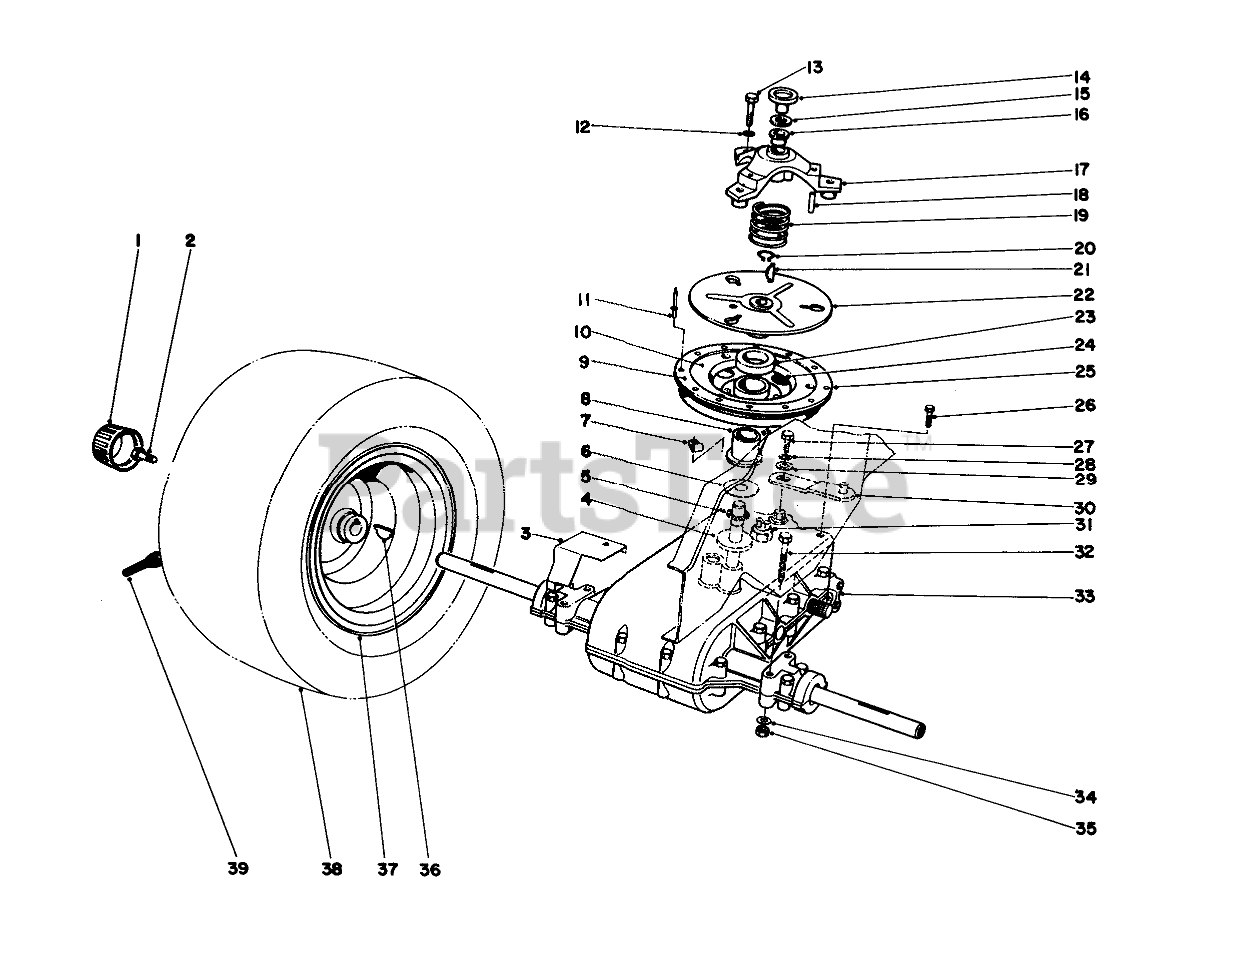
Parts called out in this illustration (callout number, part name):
1	Cap-Hub
2	CAPSCREW 3/8 16 3/4
3	GRASS SHIELD B
4	SPACER
5	NEEDLE BRG
6	THRUST WASHER
7	CLIP-FUEL LINE
9	CLUTCH PAD
10	RETAINER RING R
11	RIVET-POP
12	WASHER-LOCK
13	SCREW-HH
14	CLUTCH CAP
15	THRUST RACE
16	BUSHING-FLANGE
17	Clutch Cover (Incl. Ref. #16 & 18)
18	NEEDLE BRG
19	COMPRESSION SPRING
20	RING-SNAP, EXTERNAL
21	KEY-WOODRUFF
22	Clutch Plate
23	WASHER FELT
25	Sheave Assembly (Incl. Ref. #8-11 )
26	SCREW-HWHTF
27	SCREW-HH
28	WASHER-LOCK
29	WASHER-FLAT
30	SHIFT LEVER WA B
31	NEUTRAL SWITCH
32	SCREW-HH
33	Transaxle
34	WASHER-PLAIN
35	NUT-LOCK, CONE
37	Rim
38	16 X 7.5-8 REAR TIRE
39	STEM-VALVE
